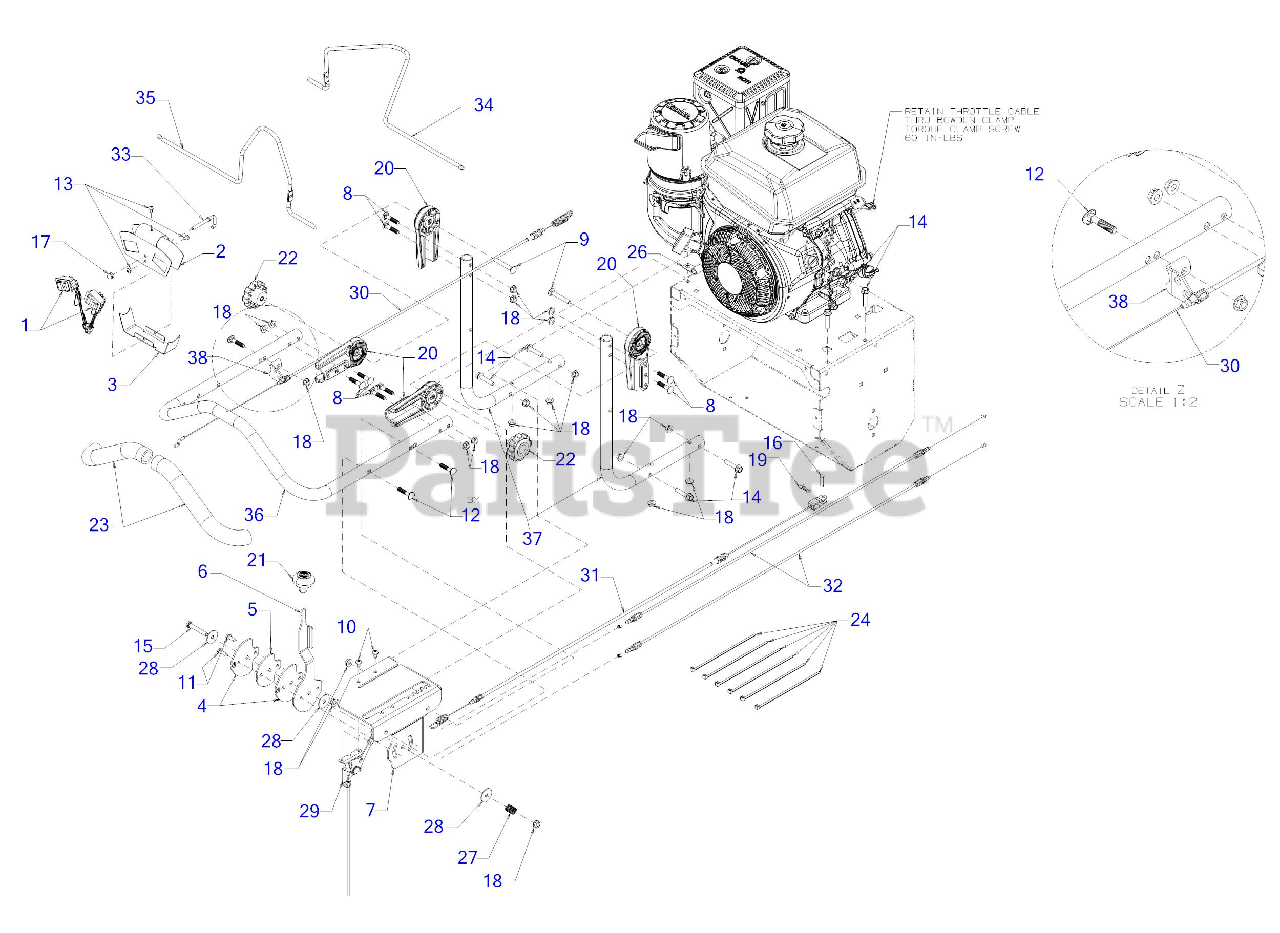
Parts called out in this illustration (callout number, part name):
1	CONTROL SWITCH ASSEMBLY
2	SWITCH MOUNTING BRACKET
3	SWITCH COVER BLOWER
4	PLATE-PULLEY CABLE GUIDE
5	PLATE-CABLE PULLEY
6	LEVER-SPEED CONTROL
7	BRACKET-SPEED CONTROL
8	CARRIAGE BOLT 5/16-18 x 1.50
9	SCRE W5/16-18 x 2.25 GR5
10	SCREW 1/4-20 x .5
11	SCREW 1/4-20 x .750
12	CARRIAGE BOLT 5/16-18 x 1.5
13	TORX SCREW #10-16 - .500
14	SCREW 5/16-18 x 1.50 GR5
15	SCREW 5/16-18 x 2.0 GR5
16	CLEVIS PIN .25 x 1.00
18	FLANGE NUT
19	BOW TIE COTTER PIN 1/4-5/16
20	HANDLE ADJUST
21	SHIFT KNOB
22	KNOB-5/16-18
23	UPPER HANDLE GRIP
24	7" CABLE TIE
26	J TYPE CLIP
27	COMPRESSION SPRING
28	FLAT WASHER .322 ID x 1.25 x .060
29	THROTTLE CABLE 38.5"
30	CLUTCH CABLE
31	BRAKE CABLE
32	SPEED SELECT CONTROL CABLE
33	PARKING BRAKE HOOK ROD
34	BLOWER CLUTCH BAIL
35	BLOWER BRAKE BAIL
36	UPPER HANDLE TUBE
37	LOWER HANDLE TUBE
38	CABLE MOUNT BRACKET
